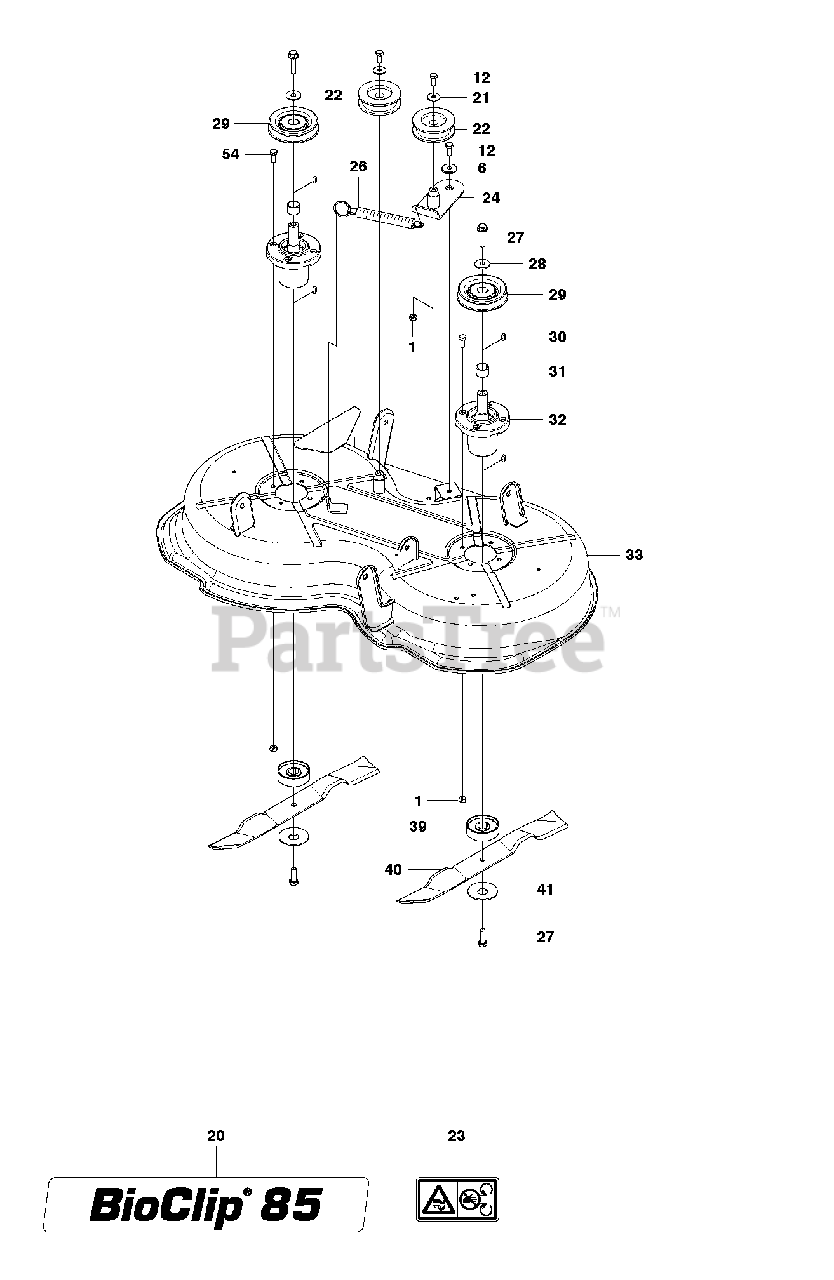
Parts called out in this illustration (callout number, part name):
1	LOCKNUT M8
12	SCREW
32	BEARING HOUSING ASSY
